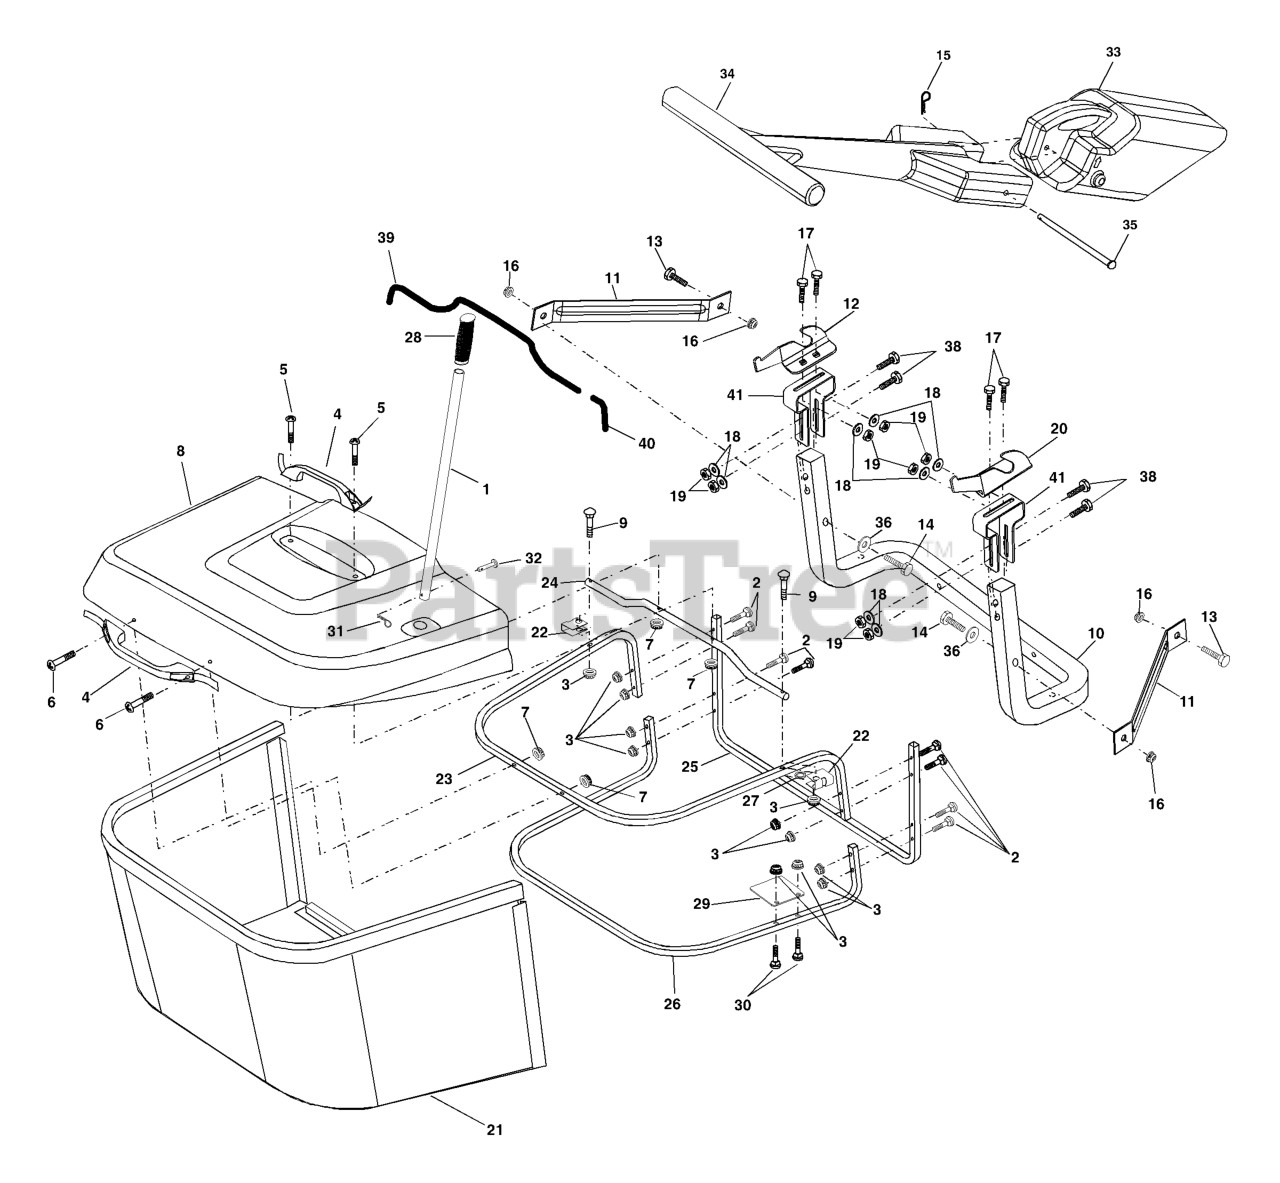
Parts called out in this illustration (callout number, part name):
1	TUBE HANDLE
2	Bolt Carriage 1/4-20 x 2.0 Gr.5
3	NUT T
4	HANDLE.BAGGER.W/LVRS.BLK.CRD
5	SCREW.PAN.HEAD
6	REPL BY 532 75 00-29
8	COVER
9	Bolt Carriage 1/4-20 x 2.25d x Gr.5
10	TUBE
11	BRACKET.SUPPORT.UPPER.BAG.CRD
13	BOLT
14	Bolt Hex 3/8-16 x 2-1/2 Gr.5
15	RETAINER-SPRNG RB
16	NUT LOCK FLG 3/8-16 UNC
17	RP BOLT 5/16-18 X3/4 ZN/YEL GR
18	WASHER M
19	NUT.71038.31-18.HEX.NYLOCK
20	BRACKET
21	BAG
22	BRKT.SIDE.BAG.CRD
23	TUBE.UPPER.BAG.CRD
24	TUBE.PIVOT.BAG.CRD.BLACK
26	TUBE.LOWER.BAG.CRD
28	GRIP.HANDLE.BLACK
30	Bolt Carriage 1/4-20 x 1 Gr.5
31	RETAINER M
32	RIVET,DRILLED
33	PLUG.MULCHER.92 CRD
34	HANDLE.MULCHER.92.CRD (2 2)
36	WASHER
38	BOLT.5/16-18X2.5
39	TRIM
40	TRIM
41	BRKT.VERT.ADJ.BAGGER.CRD
